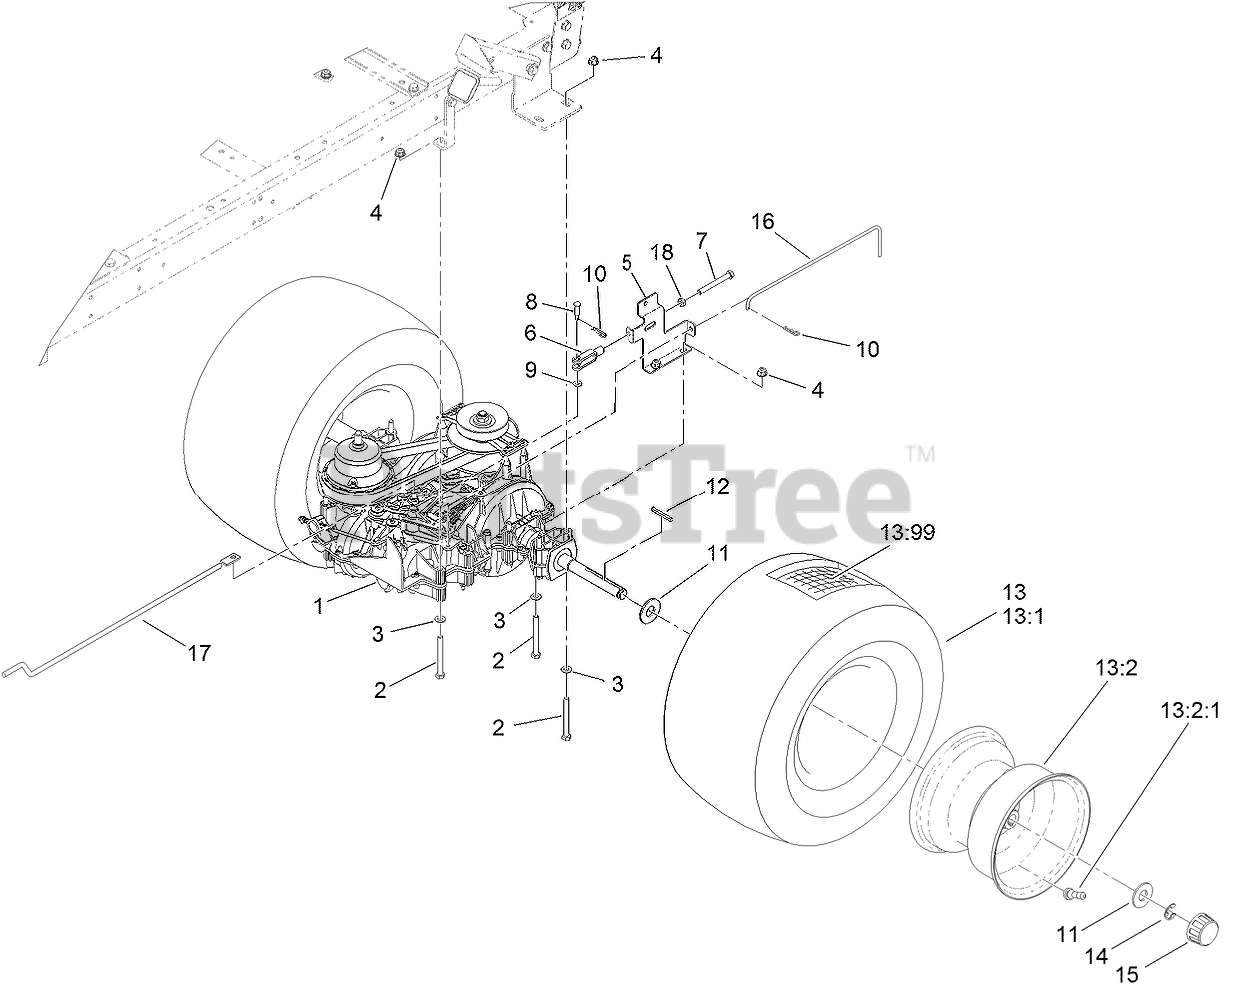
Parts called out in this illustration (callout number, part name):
1	TRANSMISSION ASM
2	SCREW-HH
3	WASHER-PLAIN
4	NUT-HF, NI
5	BRACKET-NEUTRAL
6	YOKE-ADJUSTABLE
7	SCREW-HH
9	WASHER-FLAT
10	PIN-COTTER
11	WASHER-PLAIN
12	KEY-SQUARE
13	REAR WHEEL AND TIRE ASM
13:1	TIRE
13:2:1	STEM-VALVE
13:99	Tube
14	E-RING
15	CAP-HUB
16	ROD-BYPASS
17	ROD-CONTROL, MOTION
18	NUT-JAM
